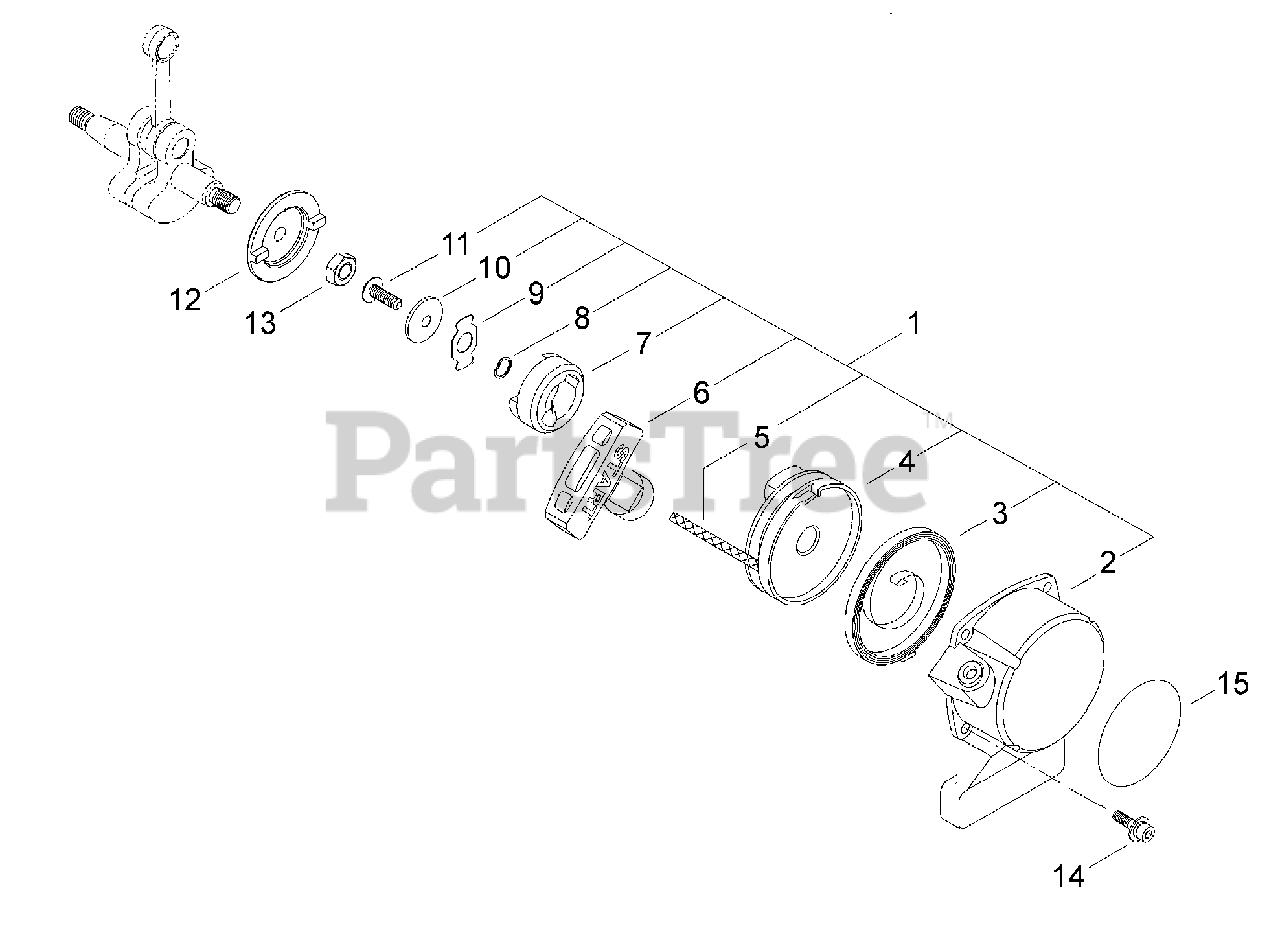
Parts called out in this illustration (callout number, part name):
1	STARTER ASSY, RECOIL
2	CASE, RECOIL STARTER
3	SPRING, RECOIL
4	REEL, ROPE
5	ROPE, STARTER
6	GRIP, STARTER
7	PAWL, STARTER
8	WASHER, WAVE
9	RETAINER
10	WASHER 5 MM
11	SCREW 5 MM
12	PULLEY, STARTER
13	NUT M8×1
14	BOLT M4×16
15	LABEL, RECOIL C4
